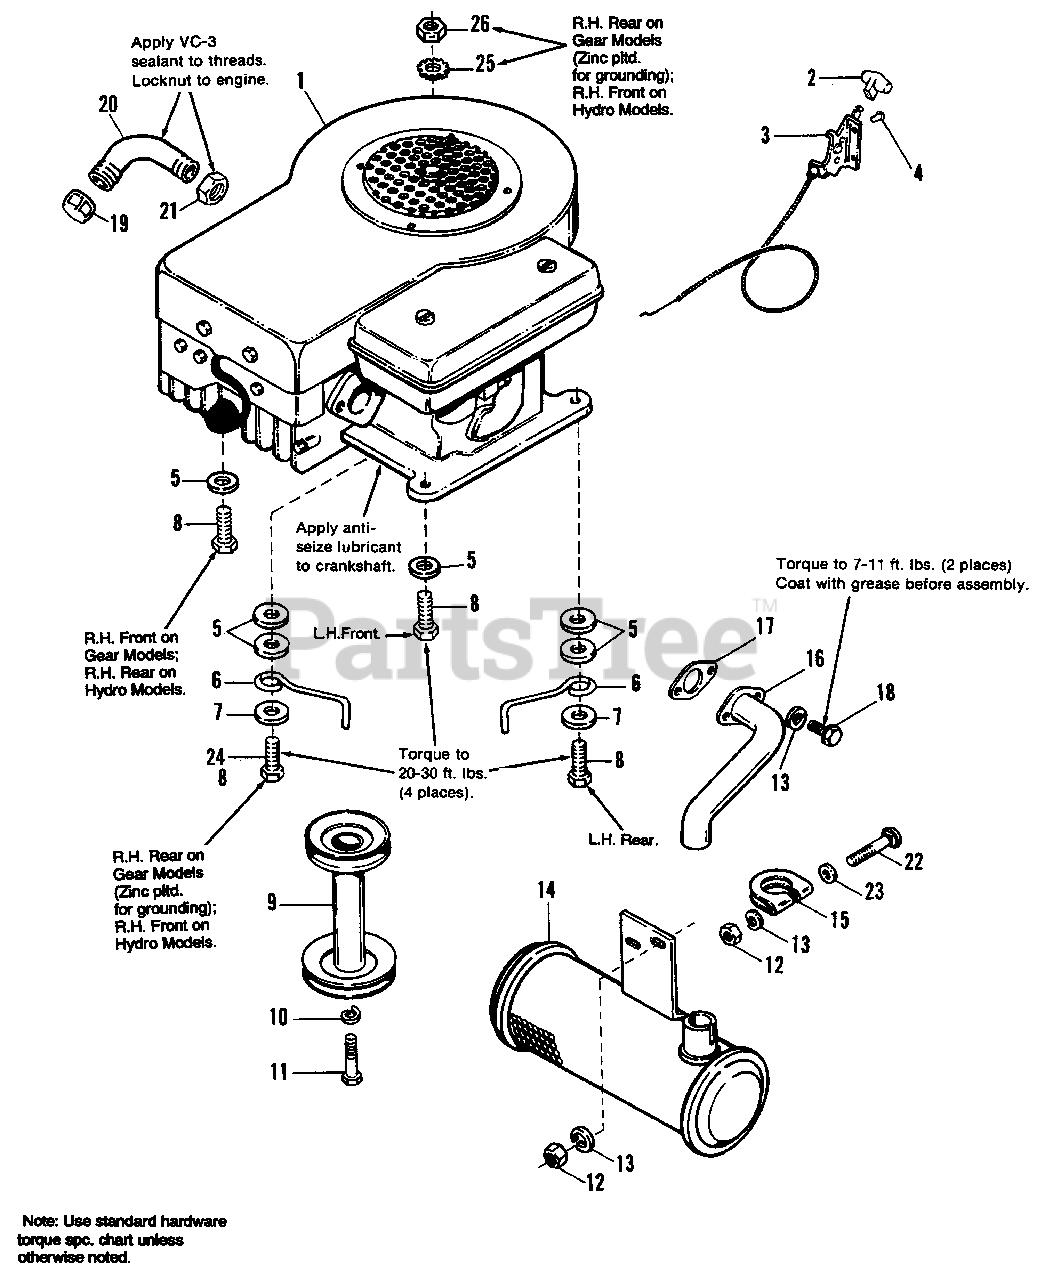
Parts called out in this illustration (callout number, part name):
1	ENGINE, 12.5 HP
2	KNOB, Throttle
3	CONTROL ASSY., Throttle
4	RIVET, Pop, 1/4
5	WASHER, Plain, 3/8
7	WASHER, 13/32
8	SCREW, Taptite, 3/8-16 x 1-1/2 (Qty. 4 on Hydro Models, Mfg. Nos. 1692156, 1692164, 1692259, 1692263))
9	PULLEY ASSY., Engine (Gear Models, Mfg. Nos. 1692160, 1692166)
9	PULLEY ASSY., Engine (Hydro Models, Mfg. Nos. 1692156, 1692164)
10	LOCKWASHER, 7/16
11	CAPSCREW, Hex, 7/16-20 x 1-1/4
12	NUT, Hex, 5/16-18
13	LOCKWASHER, 5/16
16	PIPE, Exhaust
17	GASKET, Muffler
18	SCREW, Whizlock, 5/16-18 x 3/4
20	PIPE, Oil Drain
22	BOLT, Carriage, 5/16-18 x 2-3/4 Gr. 5
24	SCREW, Taptite, 3/8-16 x 2, Zinc Pltd. (Gear Models, Mfg. Nos. 1692160, 169216S)
25	LOCKWASHER, Ext., 3/8, Zinc Pltd.
26	NUT, Hex Jam Lock, 3/8-16, Zinc Pltd. (Gear Models, Mfg. Nos. 1692160, 1692166)
